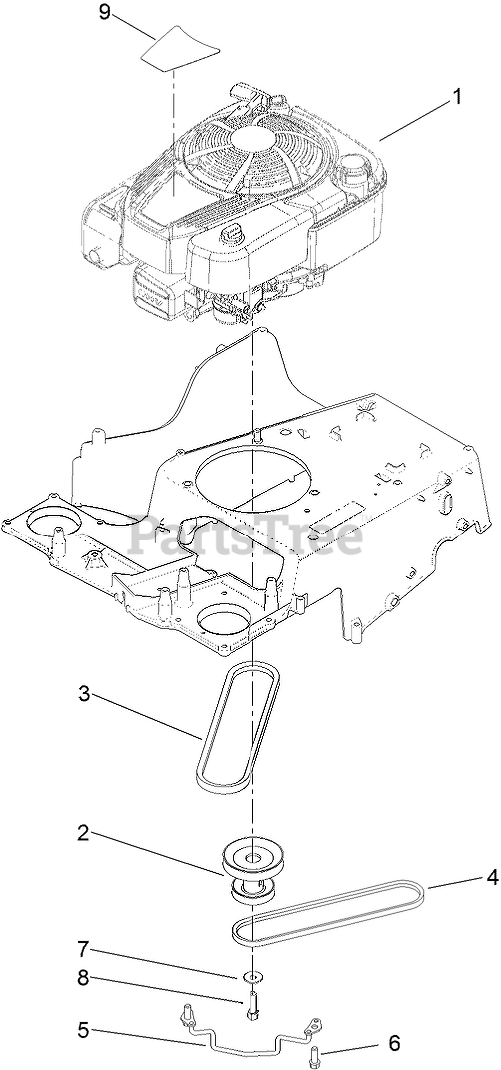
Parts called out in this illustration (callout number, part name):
2	PULLEY-ENGINE
3	V-BELT
4	V-BELT, TRACTION
5	GUIDE-BELT
6	SCREW-TAPTITE
7	WASHER-BELLEVILLE
8	SCREW-HH
9	DECAL-SHROUD
